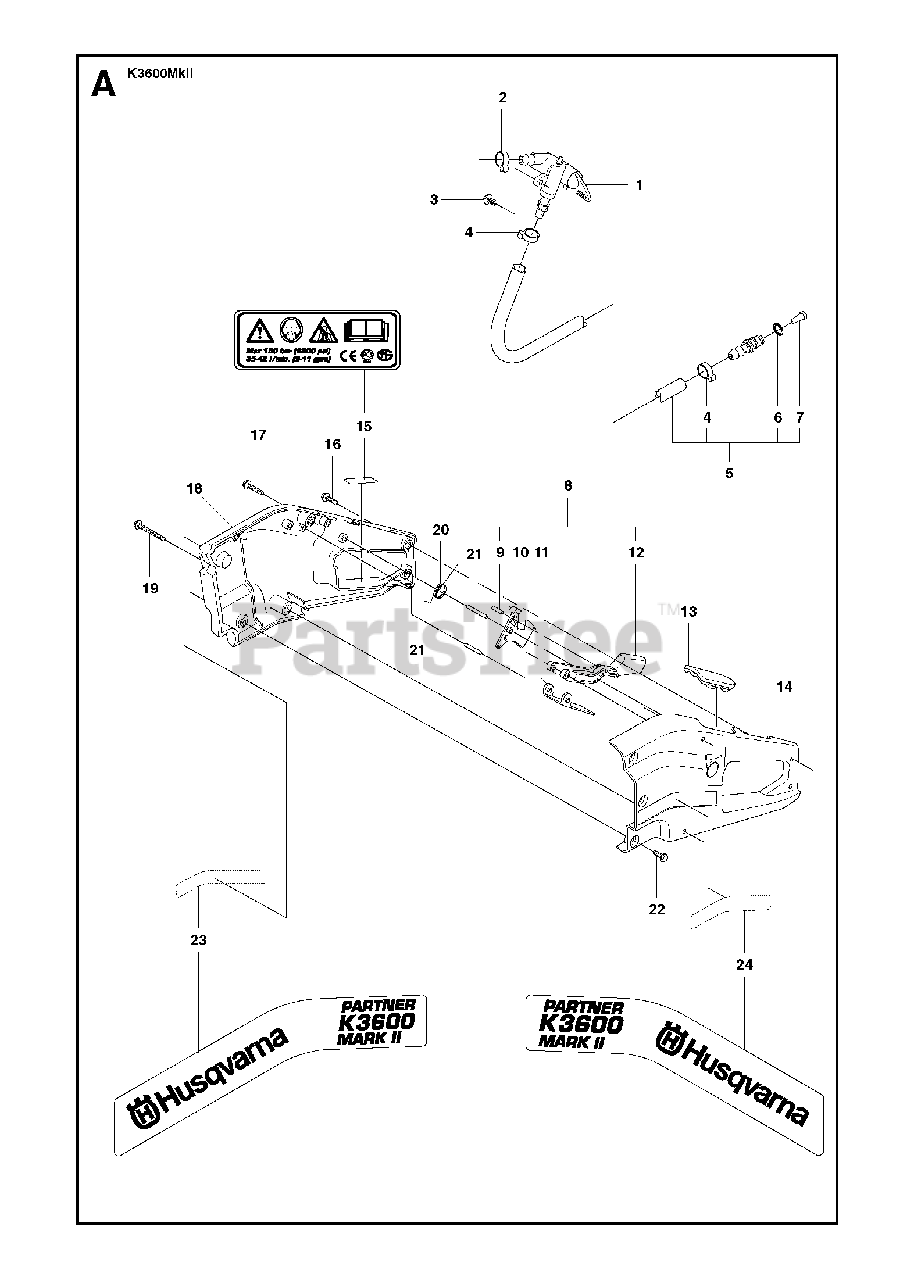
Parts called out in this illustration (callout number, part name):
2	HOSE CLAMP
4	HOSE CLAMP
5	HOSE KITIncl. 4, 6, 7
6	O-RING
8	THROTTLE TRIGGERIncl. 9, 10, 11, 12
17	SCREW EHHFM
21	PARALLEL PIN
